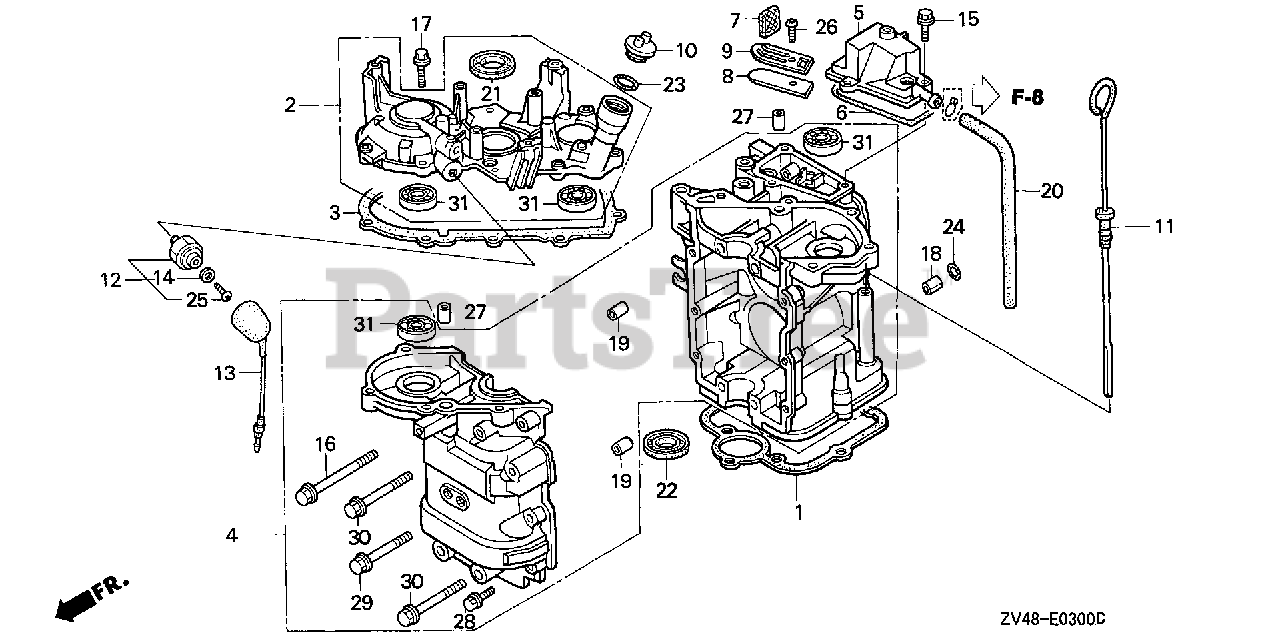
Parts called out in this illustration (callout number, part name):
1	GASKET, OIL CASE
2	CASE ASSY., STARTER *NH8* (DARK GRAY)
3	GASKET, STARTER CASE
4	CYLINDER ASSY. *NH8* (DARK GRAY)
5	COVER, BREATHER *NH8* (DARK GRAY)
6	GASKET, BREATHER COVER
7	FILTER, BREATHER
8	PLATE, VALVE
9	STOPPER, VALVE
11	DIPSTICK, OIL
12	SWITCH, OIL PRESSURE
13	WIRE, OIL PRESSURE SWITCH
14	WASHER (4MM)
15	BOLT, FLANGE (6X20)
16	BOLT, FLANGE (8X75)
17	BOLT, FLANGE (6X25)
18	PIN, SPECIAL (6.5X10)
19	PIN, DOWEL (10X12)
20	TUBE, BREATHER
21	OIL SEAL (32X44X7)
22	OIL SEAL (30X42X7)
23	O-RING (26X2.7)
24	O-RING (6.8X1.9)
25	SCREW, PAN (4X6)
26	SCREW, PAN (5X10)
27	PIN A, DOWEL (8X12)
28	BOLT, FLANGE (6X25)
29	BOLT, FLANGE (6X50)
30	BOLT, FLANGE (8X65)
31	BEARING, RADIAL BALL (6001)
